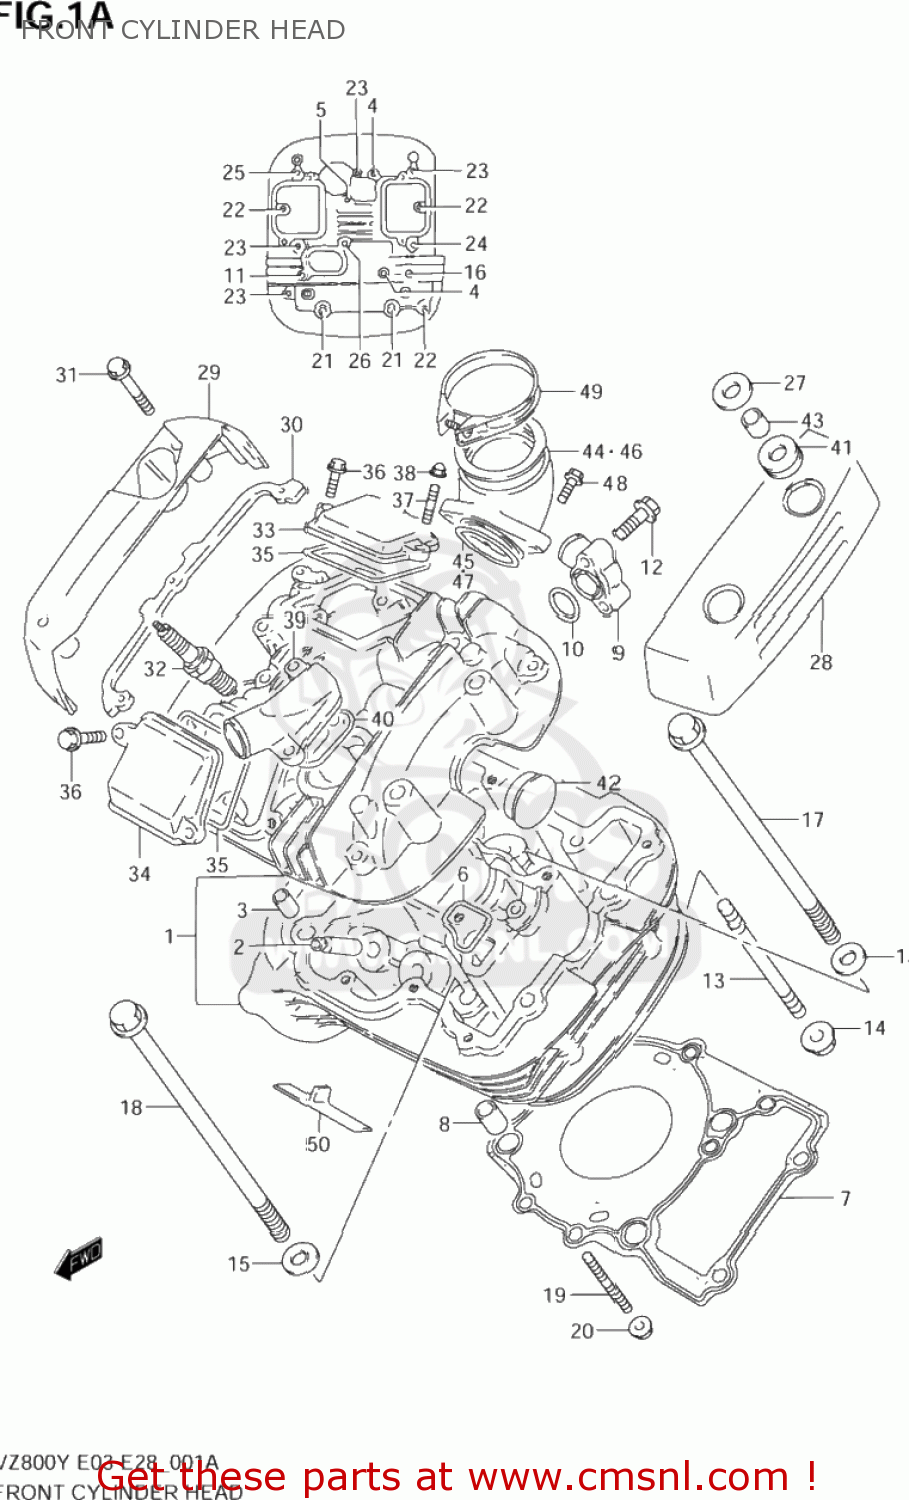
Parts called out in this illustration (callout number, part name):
1	HEAD ASSY,CYLINDER FR
2	PIN(8.4X11X14)
3	BOLT(6X50)
4	BOLT(6X55)
5	GUIDE,VALVE
6	GASKET,CYLINDER HEAD WATER (NAS)
7	GASKET,CYLINDER HEAD FR (NAS)
8	PIN
9	UNION,CYLINDER HEAD WATER
10	O RING(D:2.4,ID:17.8)
11	BOLT
12	SCREW
13	BOLT,STUD
14	NUT
15	WASHER(10.5X22X2.3)
16	BOLT(8X140)
17	BOLT(10X155)
18	BOLT(10X165)
19	STUD BOLT
20	NUT
21	BOLT(8X245)
22	BOLT
23	BOLT
24	BOLT
25	BOLT
26	BOLT(6X55)
27	WASHER(8.5X24X1.6)
28	CAP,CYL HEAD COVER,FL & RR
29	CAP,CYLINDER HEAD COVER,F-R
30	CUSHION,FR,R CAP
31	BOLT(6X40)
32	SPARK PLUG X22E
33	CAP,INSPECTION INTAKE
34	CAP,INSPECTION EXHAUST
35	GASKET,INSPECTION CAP (NAS)
36	BOLT
37	STUD 6X16
38	NUT
39	UNION,WATER OUTLET
40	GASKET,WATER OUTLET UNION (NAS)
41	CUSHION
42	PLUG(OD:30)
43	BUSH
44	PIPE,INTAKE,FRONT
45	O RING(D:2.4,ID:39.7)
46	PIPE ASSY,INTAKE FR
47	O RING(D:2.4,ID:39.7)
48	BOLT
49	CLAMP
50	PLATE,HEAD COVER RR
